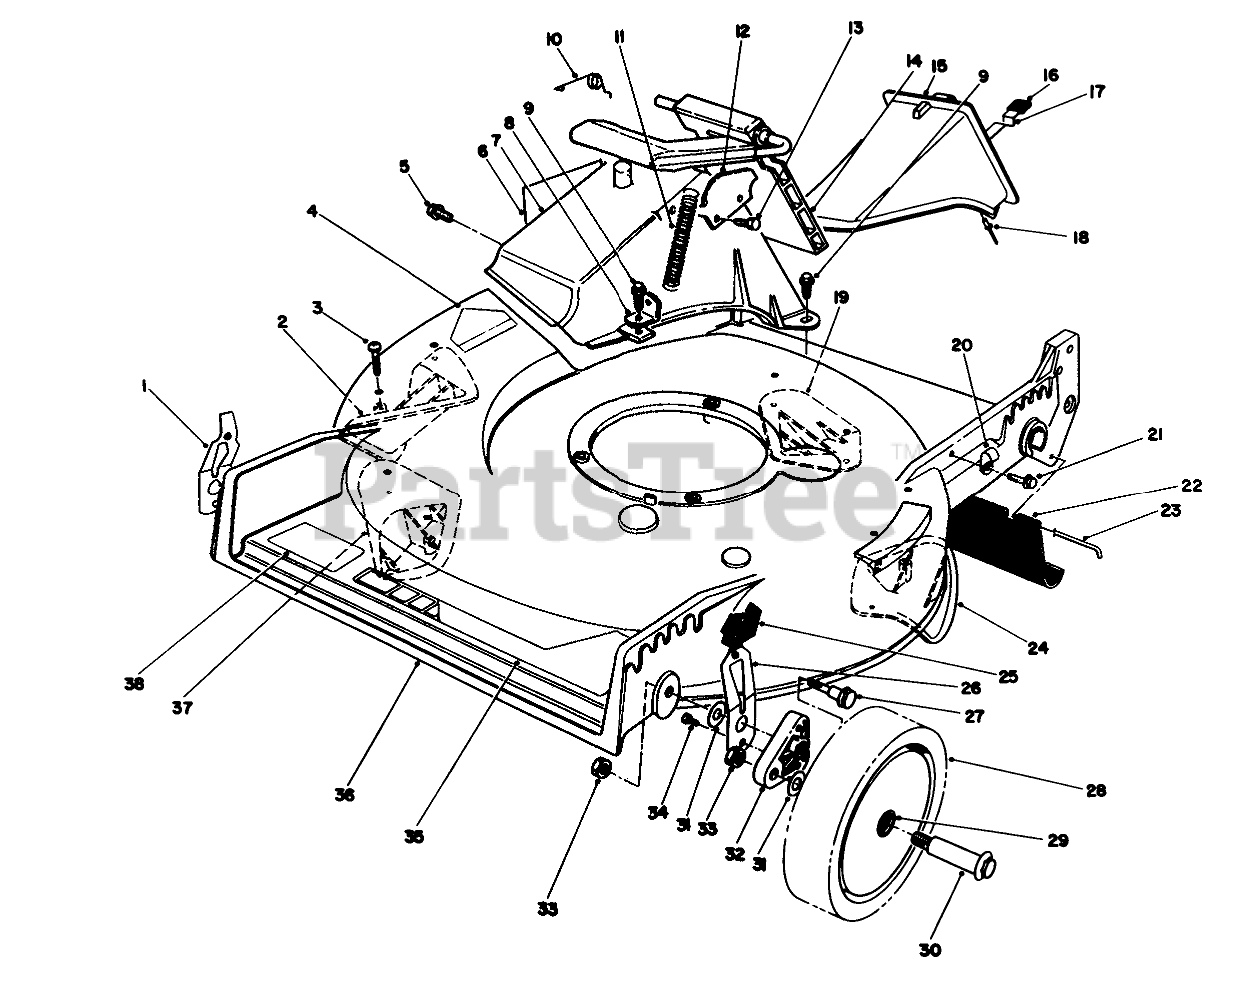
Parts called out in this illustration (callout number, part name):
1	RH SPRING ARM ASSEMBLY
2	KICKER
3	SCREW-PPH
4	DECAL-DANGER
5	SCREW AND WASHER ASM
6	DECAL - DANGER
7	TUNNEL-DISCHARGE
8	Bracket-Spring
9	SCREW-HWH
10	RETAINER-DOOR
11	SPRING-DOOR
12	DOOR LATCH PLATE
13	SCREW-PLASTITE
14	DOOR ASSEMBLY
15	Discharge Plug Assembly (Incl. Ref. #16-18)
16	GRIP-LATCH
17	LATCH-PLUG, DISCHARGE
18	RIVET-HEAD, FLAT
19	PLATE-KICKER
20	CLAMP-R
21	SCREW-HWH
22	SHIELD-TRAILING
23	ROD-SHIELD
24	KICKER
25	KNOB-ARM
26	LH SPRING ARM ASSEMBLY
27	SCREW-SHOULDER
28	Wheel & Tire Assembly (Incl. Ref. #29)
29	BUSHING
30	WHEEL BOLT
31	WASHER
32	ARM-PIVOT, FRONT
33	Nut
34	SCREW-HWH
35	DECAL - DECK
36	Housing Assembly (Incl. Ref. #2-4, 19, 24, & 37)
37	KICKER
38	DECAL
